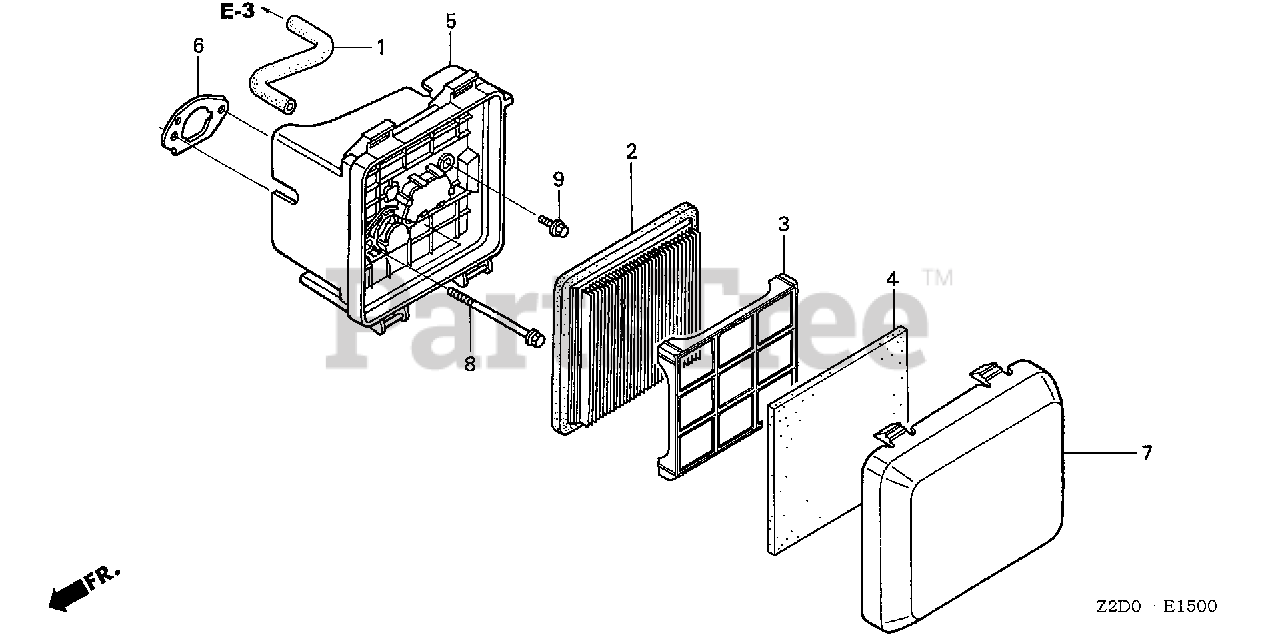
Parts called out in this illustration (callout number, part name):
1	TUBE, BREATHER
2	ELEMENT, AIR CLEANER (TOYO ROKI)
3	GRID, AIR CLEANER
4	FILTER (OUTER) (WET)
5	CASE ASSY., AIR CLEANER
6	GASKET, AIR CLEANER
7	COVER, AIR CLEANER (DUAL)
8	BOLT, FLANGE (6X86) (CT200)
9	BOLT, FLANGE (6X14)
